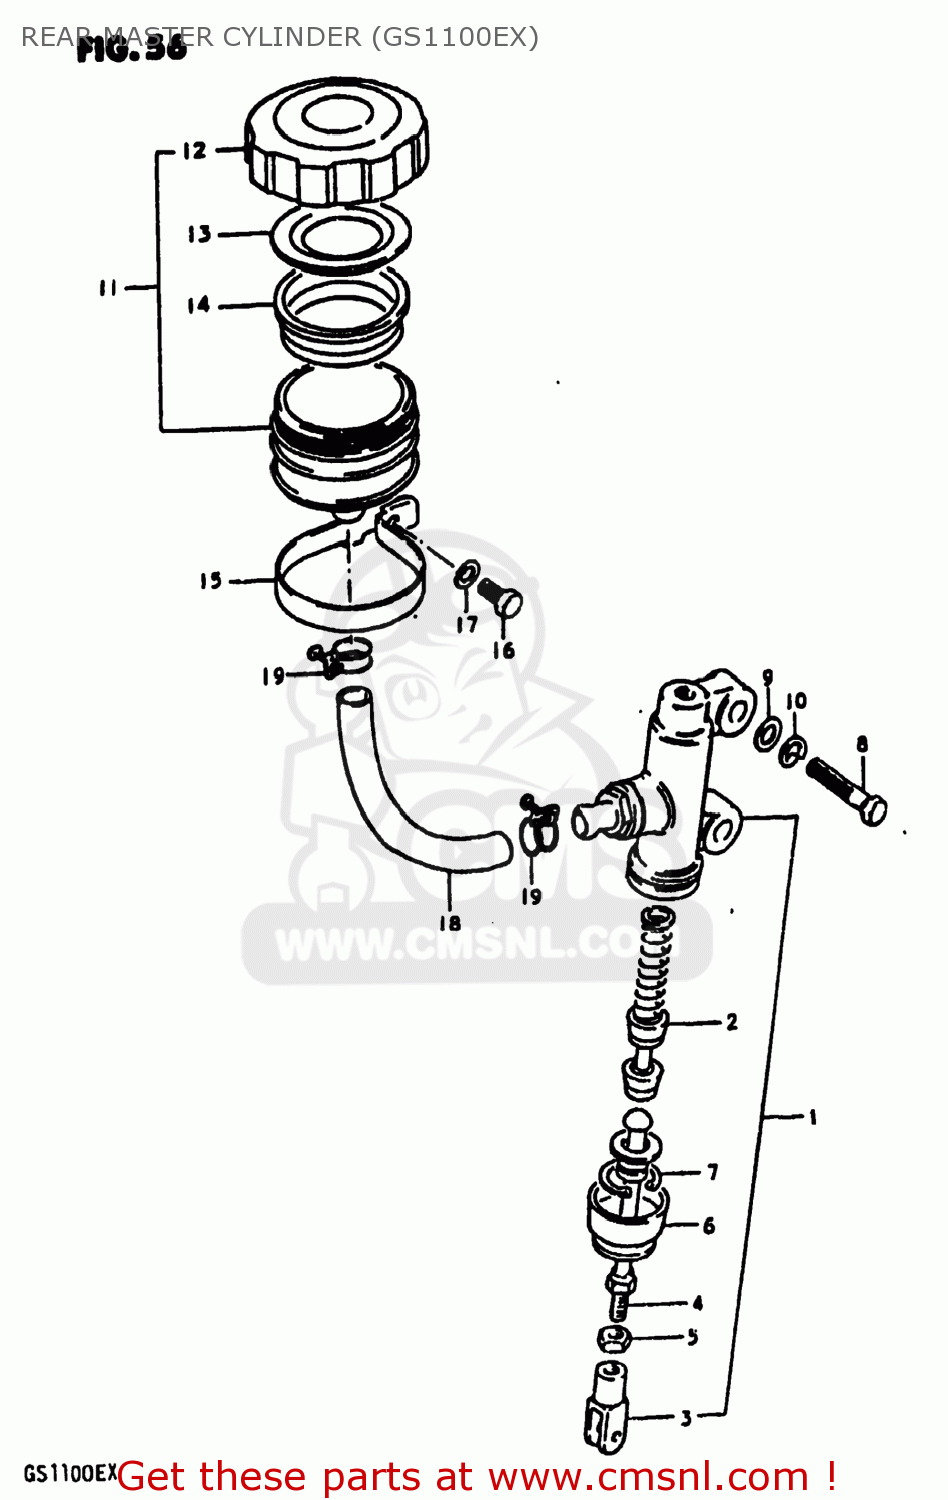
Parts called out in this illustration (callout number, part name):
1	CYLINDER ASSEMBLY,REAR MASTER
2	PISTON/CUP SET
3	YOKE
4	ROD,PUSH
5	NUT
6	BOOT
7	CIRCLIP
8	BOLT (8X30)
9	WASHER
10	LOCK WASHER
11	TANK ASSEMBLY,RESERVOIR
12	CAP
13	PLATE,DIAPHRAGM
14	DIAPHRAGM
15	CLAMP
16	BOLT, UPPER
17	LOCK WASHER
18	HOSE,RESERVOIR TANK
19	CLAMP
